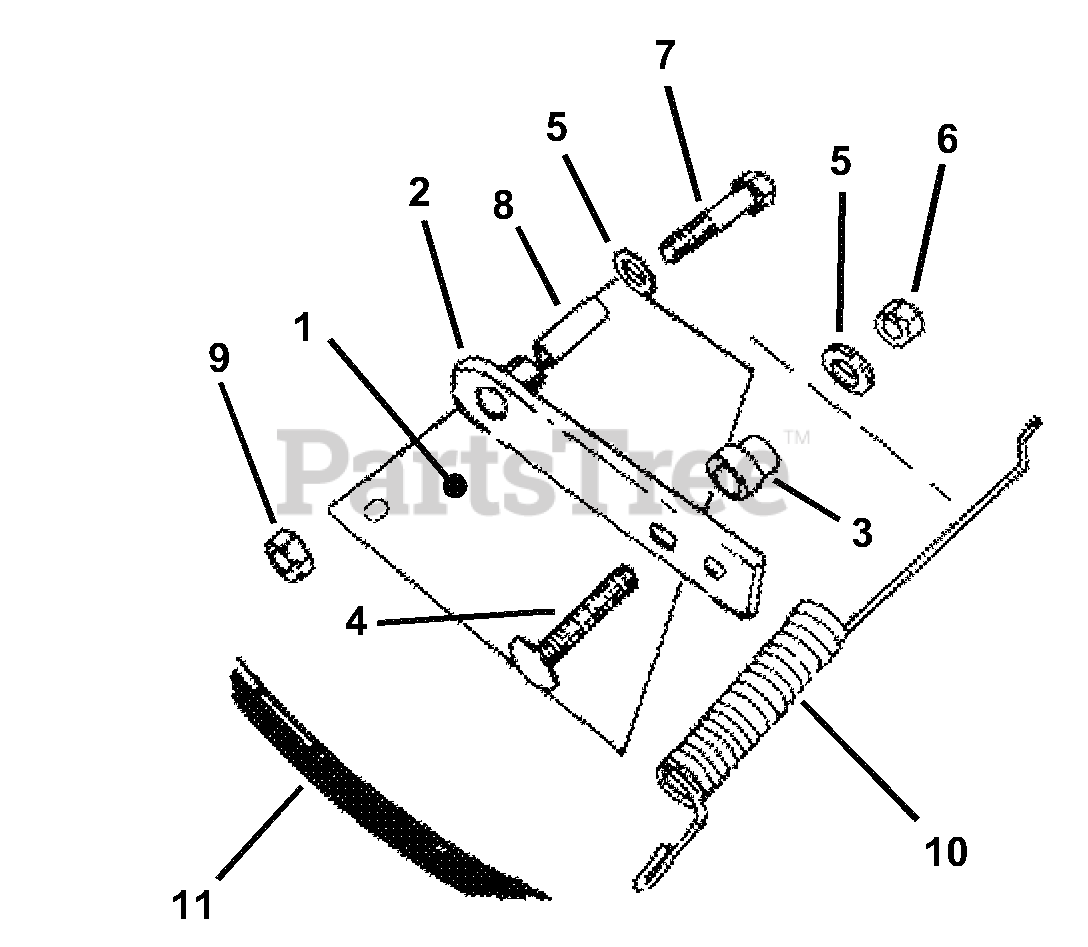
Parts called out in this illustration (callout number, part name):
1	SHIELD, Adjusting Slot Cover
2	ARM, Idler (weldment)
4	BOLT, 3/8-16 x 1-1/2" Square Neck Carriage
5	WASHER, 3/8" SAE Flat
6	NUT, 3/8-16 Hex
7	SCREW, 3/8-24 x 2" Hex Head Cap
8	BUSHING
9	NUT, 3/8-Hex Center Lock
11	BELT, HBX Sect. 89.625" Effective Length
